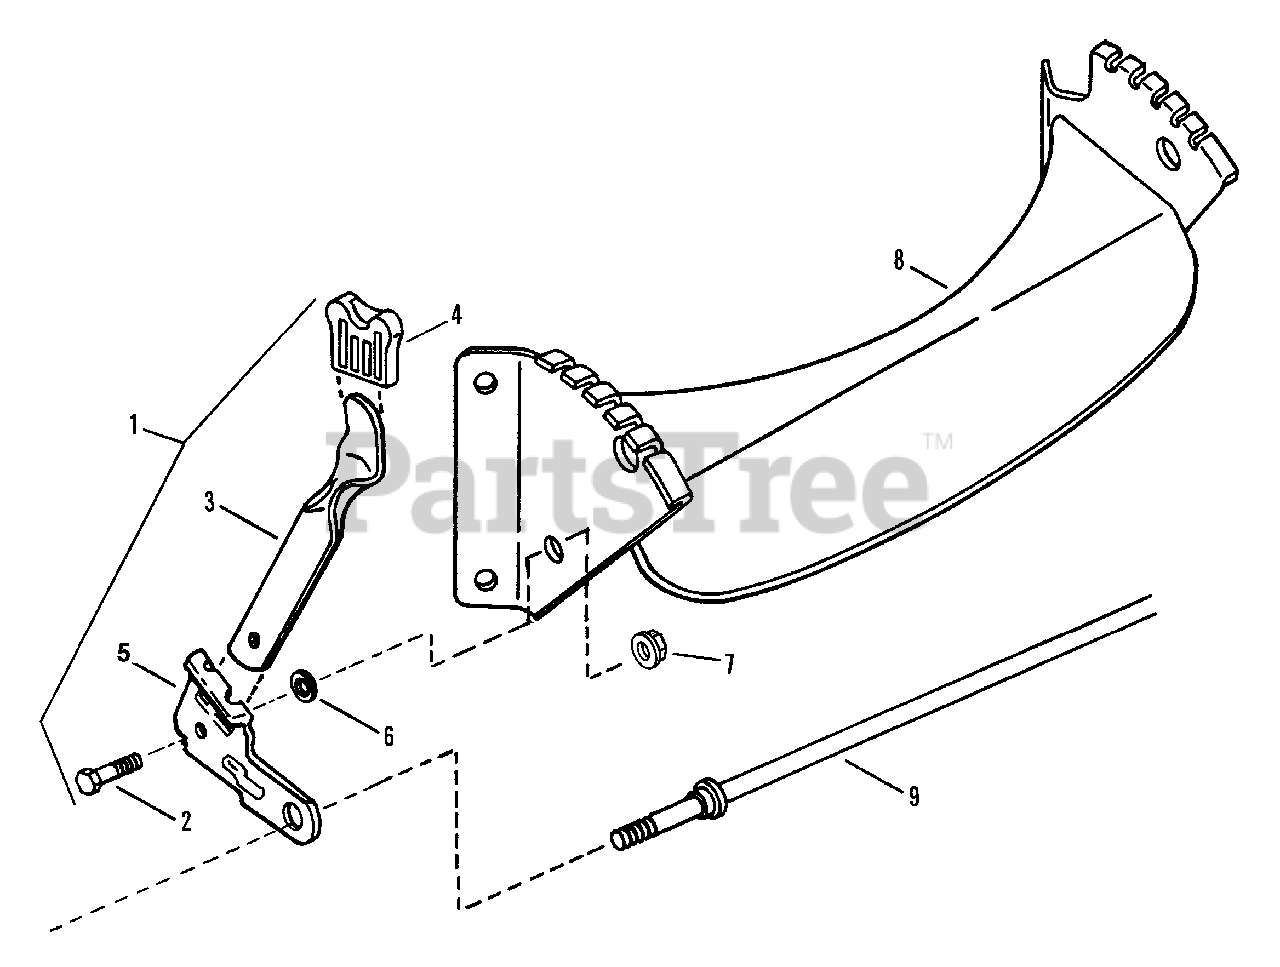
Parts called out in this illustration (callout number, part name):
1	ASSEMBLY, Arm Right Wheel
2	BOLT, 5/16-18 x 3/4" Shoulder
3	LATCH, Height
4	GRIP, Latch
5	ARM, Right Wheel
6	RETAINER, 5/16 Bolt
7	NUT, 5/16-18 Hex Flange
8	BRACKET, Front Wheel
9	AXLE
